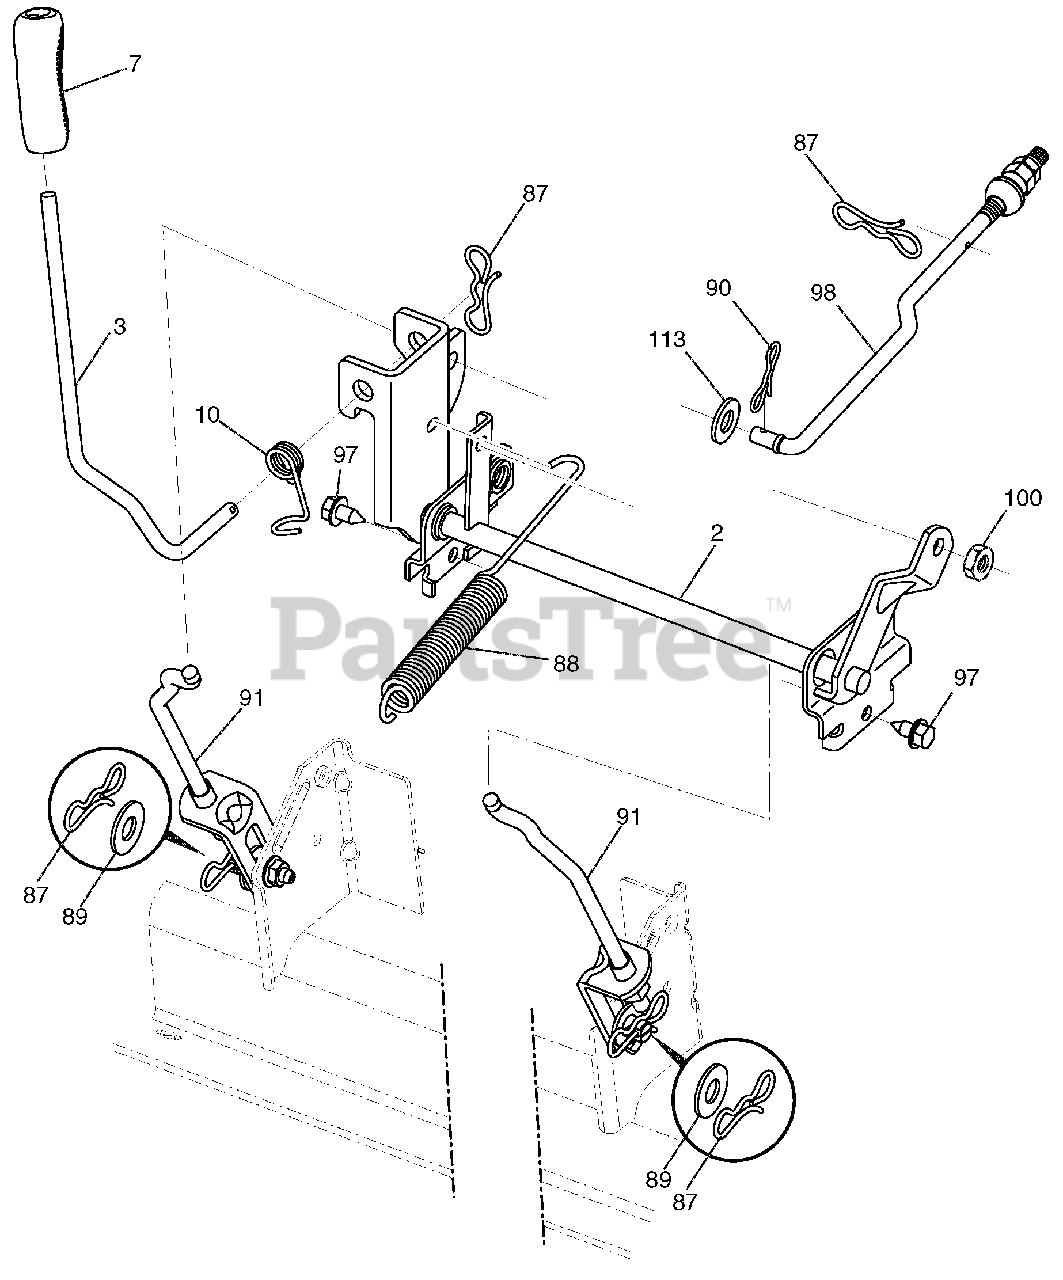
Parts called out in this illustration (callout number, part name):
2	SHAFT ASM.LIFT.CROSS.HD.
3	LEVER.LIFT.HANDLE.LT
7	GRIP.LEVER..5625 ID.BLACK 428
10	SPRING.TORSION.HANDLE.LIFT
87	PIN.COTTER.7/16.BOW TIE LOCK
88	SPRING.LIFT ASSIST
89	WASHER.CLEAR ZINC
90	PIN.COTTER.5/16.BOW TIE LOCK
91	LINK ASM.LIFT.LH.REAR
97	SCREW.HEXWSH THDR3/8-16X3/4.BL
98	LINK ASM.SUSP.FRONT.MWR.11
100	NUT.CENTERLOCK.3/8-16 UNC.
113	WASHER.17/32 X 1-3/16 X 12 GA.
